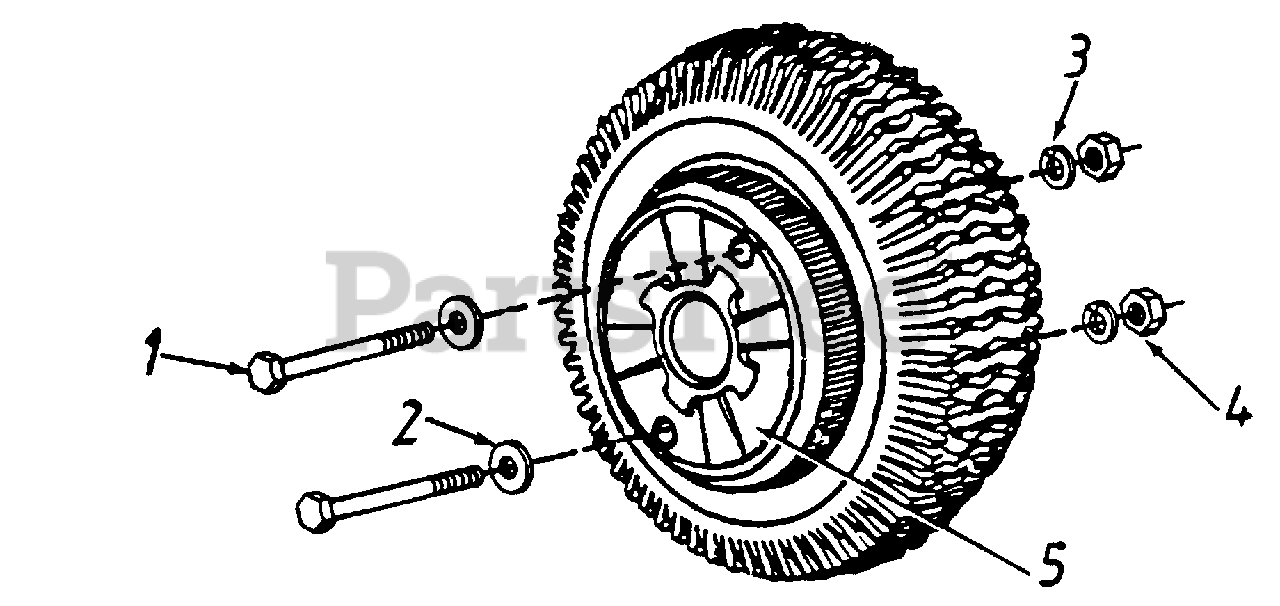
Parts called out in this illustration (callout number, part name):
1	4
2	4
3	4
4	4
5	2
